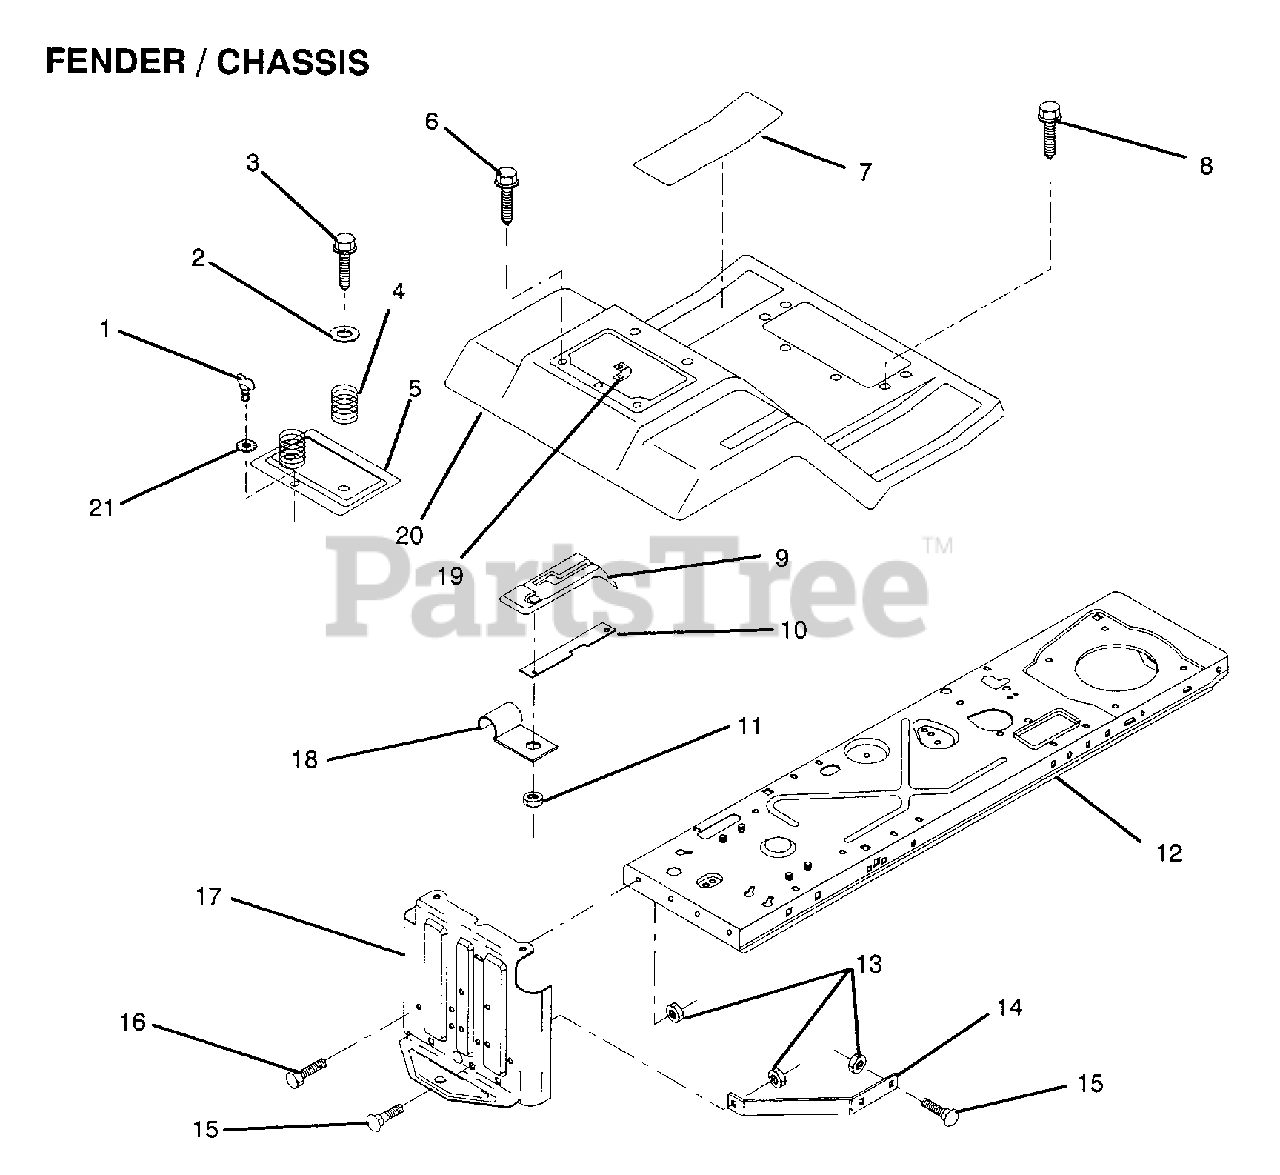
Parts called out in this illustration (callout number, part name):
1	STUD.1/4.TURN
2	WASHER
3	SCREW
4	SPRING COMPRESSIO
6	SCREW LT
7	PAD FOOTREST
8	SCREW
10	"SHIFT LOCK, BAR"
11	NUT
12	FRAME ASS'Y
14	"BRACE,DRAWBAR "
15	BOLT
16	BOLT
17	DRAWBAR
18	"CLIP,INSULATOR"
19	RECEPTACLE LT
20	"FENDER,FOOTREST T"
21	RETAINER LT
